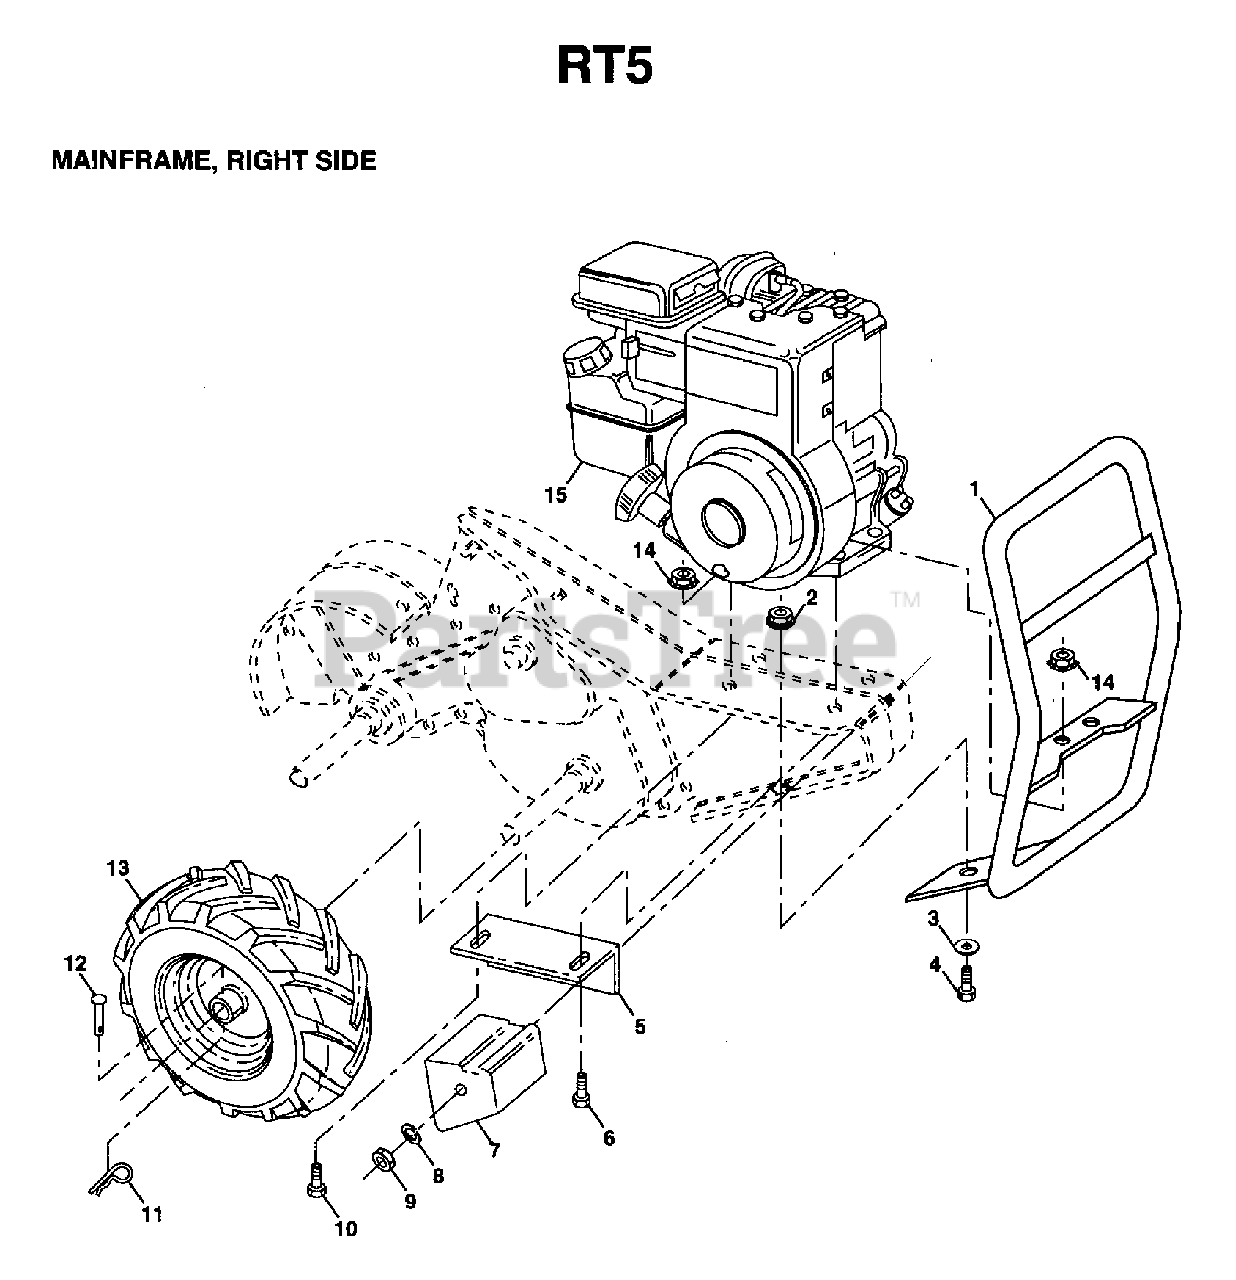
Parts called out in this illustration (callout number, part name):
2	LOCKNUT-FLANGE 5/16-18
3	WASHER
4	BOLT
5	BRACKET RH CRT
7	COUNTERWEIGHT, RH
8	WASHER, LOCK 3/8
9	NUT.HEX.3/8-16UNC
10	BOLT
11	RETAINER M
12	RIVET,DRILLED
14	NUT
5321243-66	RIM
5321247-18	VALVE STEM LT
